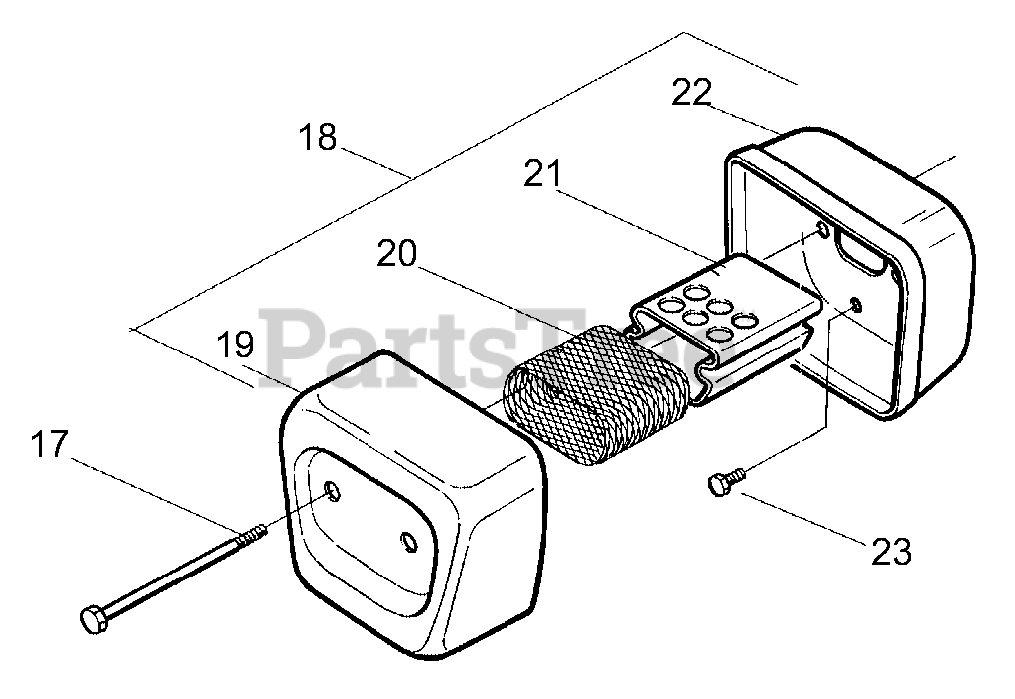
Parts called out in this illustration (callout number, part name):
18	MUFFLER KIT
19	SILENCER COVER
20	SPARK ARRESTOR 36/41
21	FLAME PROTECTOR
22	SILENCER BODY
23	BOLT-MUFFLER(SUPPORT)
